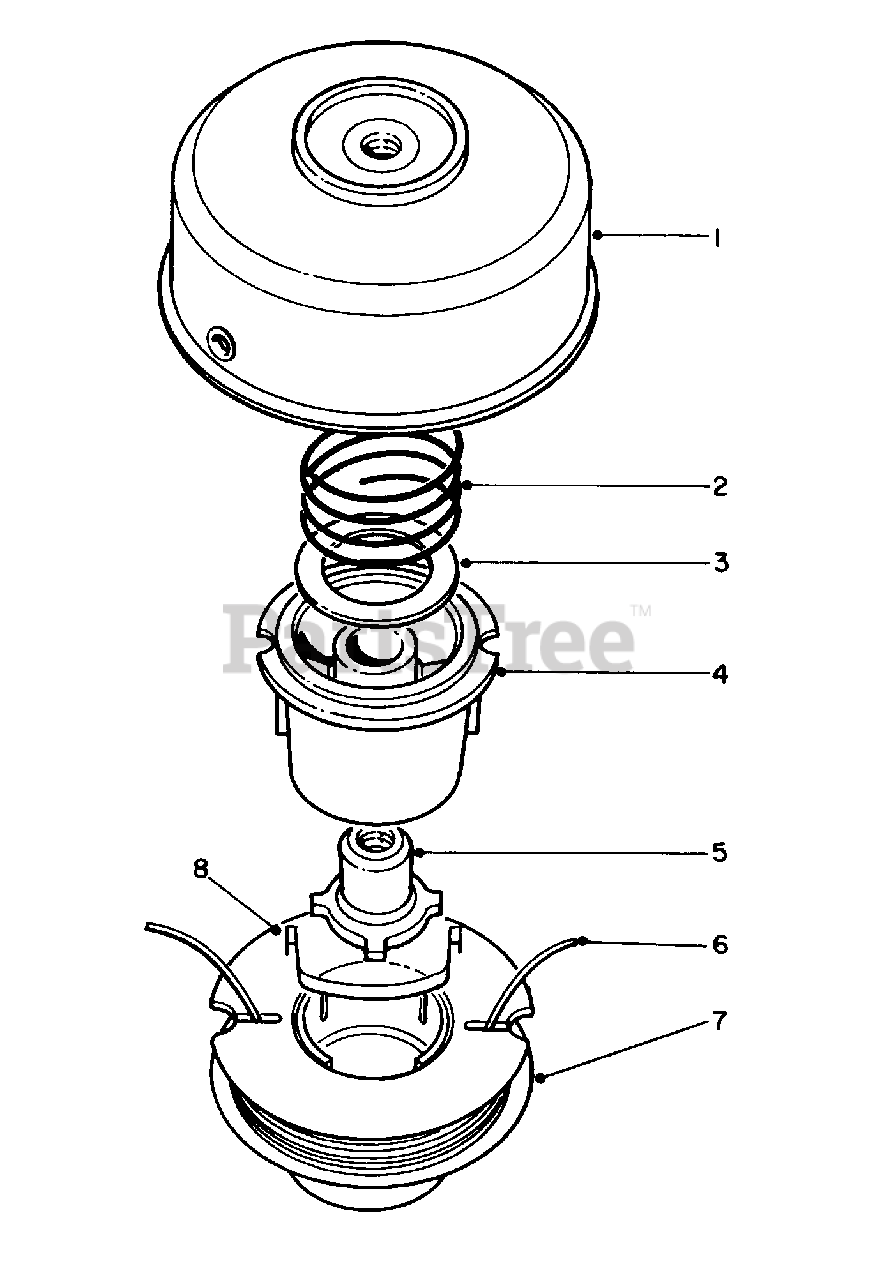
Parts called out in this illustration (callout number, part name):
1	Drum Assembly w/Eyelet
4	Spool Core
5	Driver L.H.
6	.080 Filament Line in Coil (38 ft.)
7	Prewound Spool
8	Saddle-Spool Cap
